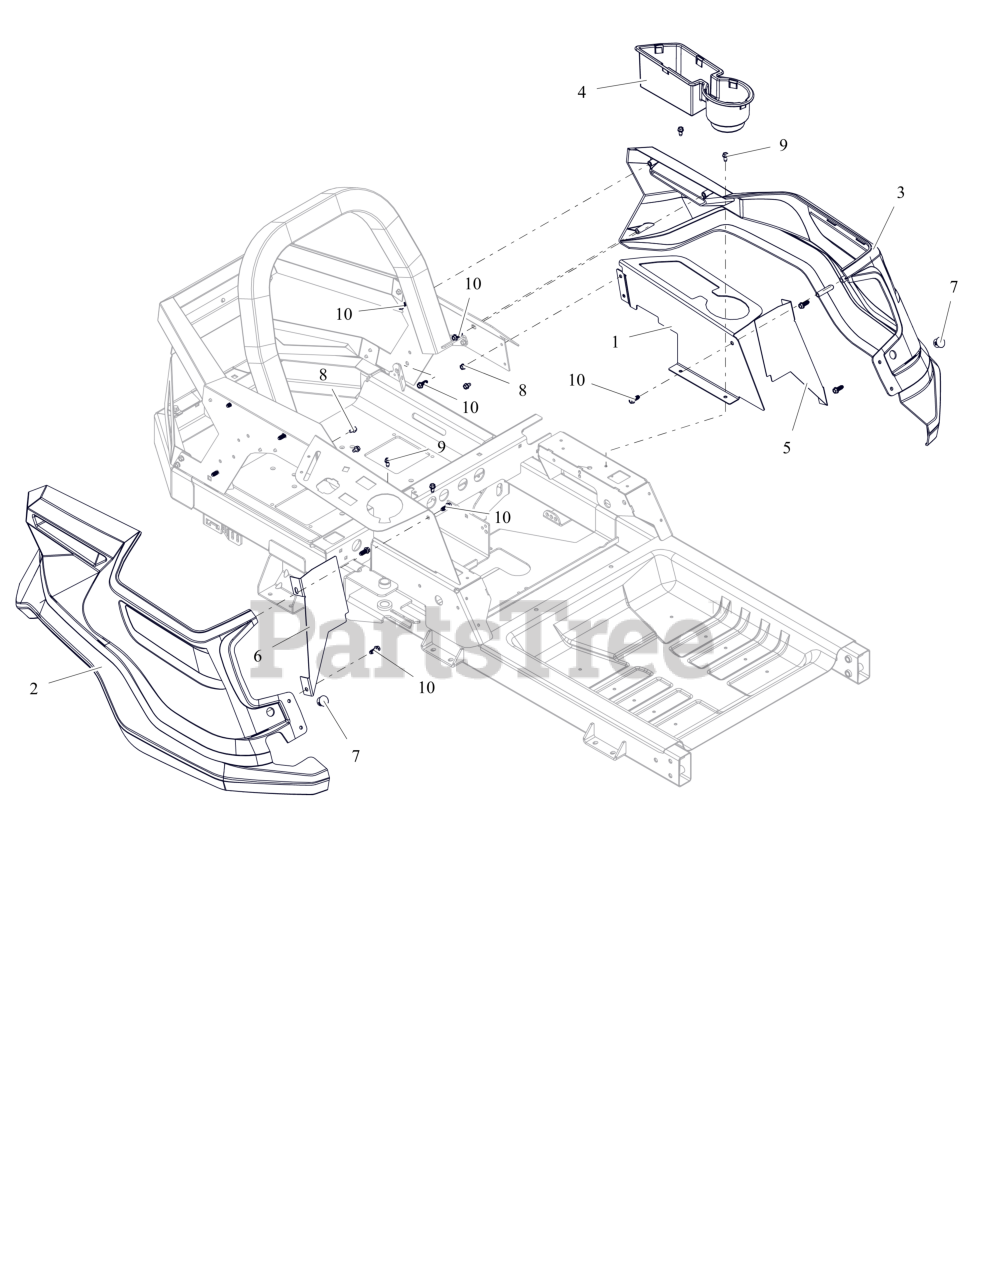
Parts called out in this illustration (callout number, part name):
1	PANEL, LEFT SIDE FENDER MOUNT
2	FENDER, RH IKON
3	FENDER, LH IKON
4	INSERT, CUP/STORAGE HOLDER
5	PLATE, LH BLOCKER
6	PLATE, RH BLOCKER
7	PLUG, HOLE .75 (BLACK)
8	SCR,TAP .25-20X.375 HWH TR ZCC
9	SCR-TAP .25-20X.50 HWH ZCC
10	SCR-.312X.75 #14H H/W/H H/L CZ
